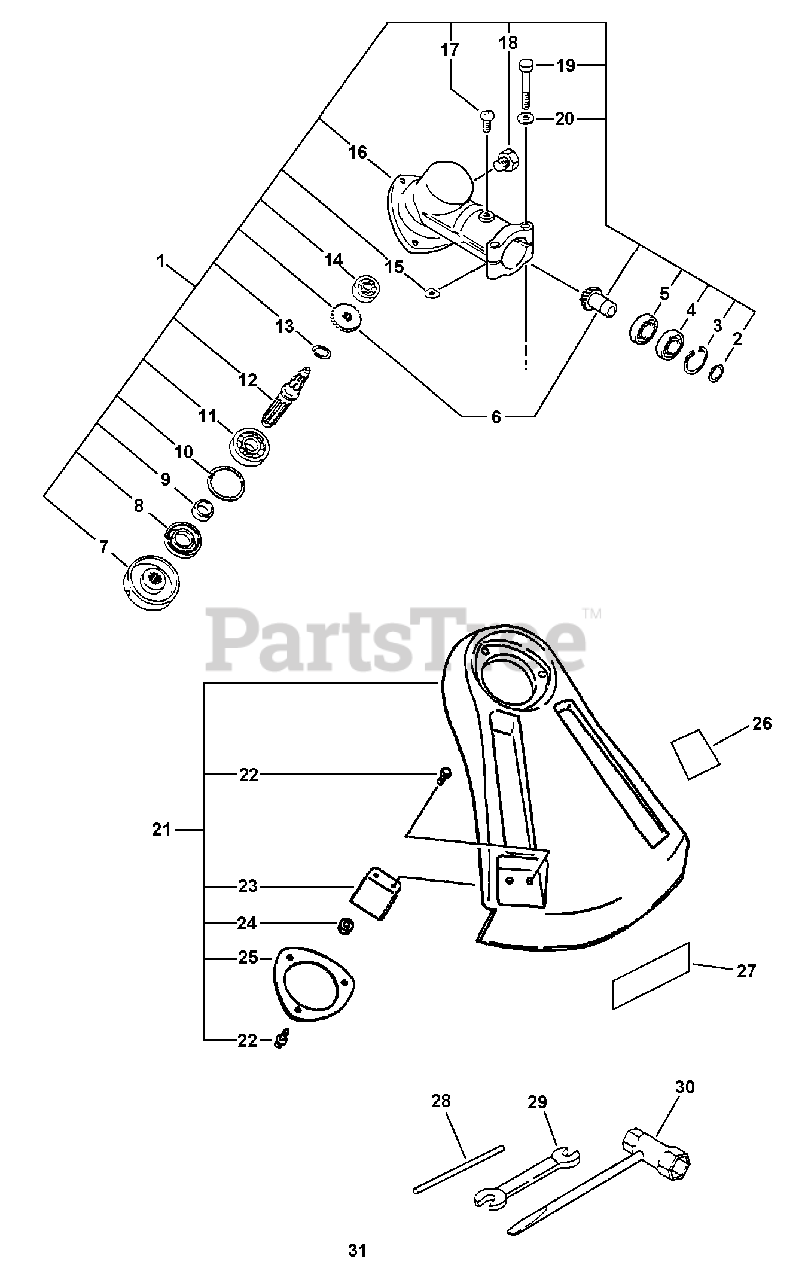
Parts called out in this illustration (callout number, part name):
1	Gear Housing Asy
2	Circlip 10
3	Circlip 22
4	Bearing, Ball 6900
5	Bearing, Ball 6900
6	Gear Set, Bevel
7	Plate, Adapter (U)
10	Circlip 32
11	Bearing, Ball 6201
12	Shaft, p.t.o.
13	Circlip 12
14	Bearing, Ball 609
15	Washer, Shim
16	Housing, Gear
17	Screw 5x10
18	Bolt 8x8
19	Bolt 5x35
20	Washer 5
21	Shield Asy
22	Screw 5x16
23	Knife, Cord
25	Bracket, Shield
26	Label, Caution
27	Label, Echo
28	Locking Tool
29	Spanner 8x10
30	Wrench, W/Screwdriver
